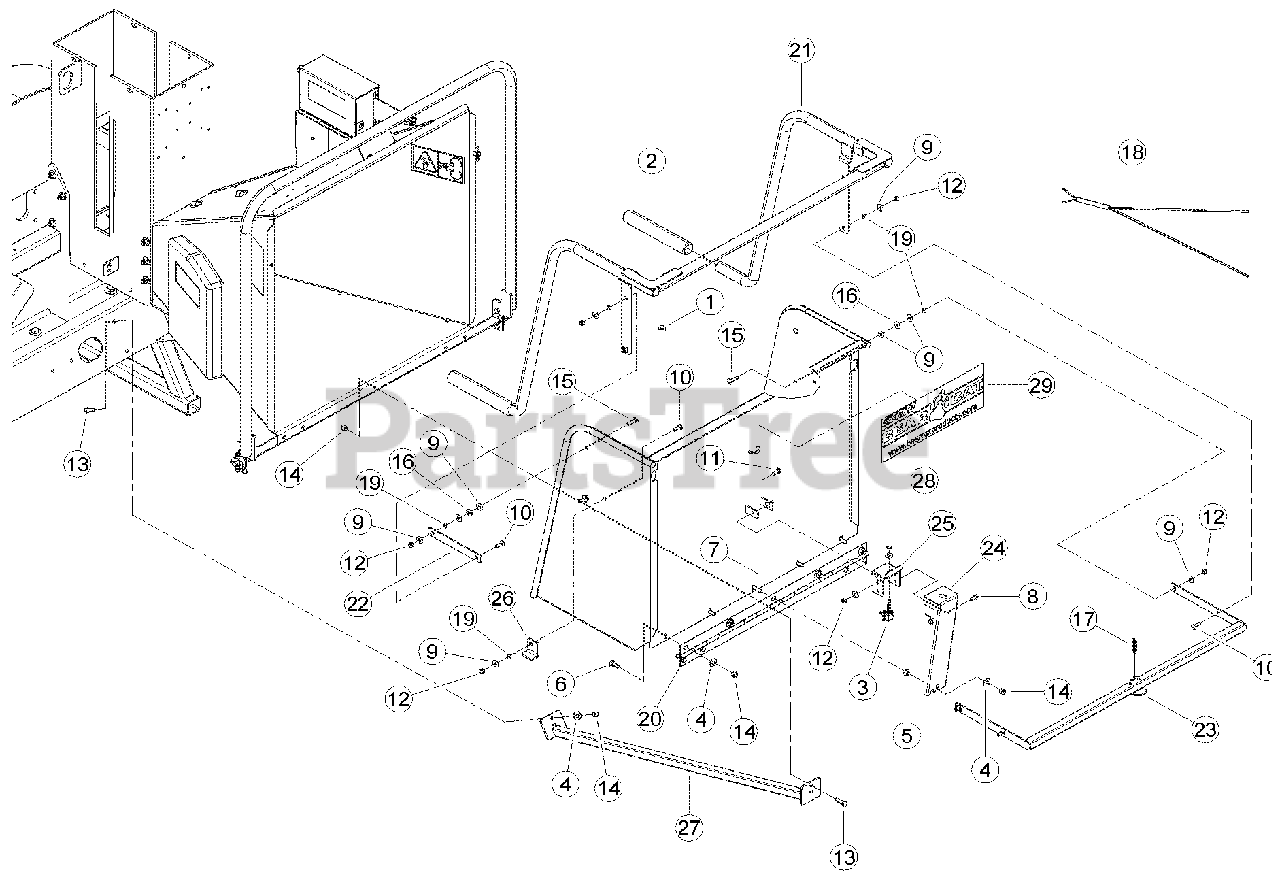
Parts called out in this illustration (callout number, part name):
1	BUMPER, RUBBER
2	GRIP, 1.219 X 10.00
3	SWITCH, MOMENTARY IP67. (FOR SERVICE ORDER KIT #77536-00)
4	WASHER, 3/8 FLAT ZP
5	NUT, 3/8 SERR FLANGE NC ZP
6	BOLT, 3/8 X 1 CRG GR5 NC ZP
7	BOLT, 3/8 X 1-1/2 CRG GR5 NC ZP
8	SCREW, 11/32 X 7/8 HWH AB THREAD ZP
9	WASHER, 5/16 FLAT ZP
10	BOLT, 5/16 X 1 CRG GR5 ZP
11	BOLT,5/16 X 7/8 CRG GR5 NC ZP
12	NUT, 5/16 NE NYLOCK ZP
13	BOLT, 3/8 X 1-1/4 HEX HD GR5 ZP
14	NUT, 3/8 NE NYLOCK ZP
15	BOLT, 5/16 X 1-1/4 CRG GR5 ZP
16	WASHER, 5/16 ID 7/8 OD NYLON FLAT
17	SPRING, 1/2 X 2.00 LONG ZP
18	HARNESS, SAFETY BAR
19	SPACER, IDLER PIVOT
20	HINGE, EXTENSION TRAY
21	WELDMENT, KNEEBAR
22	LINK, PARALLEL
23	WELDMENT, KNEEBAR PIVOT
24	SHIELD, KNEEBAR SWITCH
25	BRACKET, SWITCH. (WAS 77532-12. REPLACED AND SUPERSEDED. FOR SERVICE, ORDER KIT #77536- 0, CONTROL SWITCHES)
26	LOCK, SAFETY BAR
27	WELDMENT, CHUTE SUPPORT
28	ASSEMBLY, EXTENSION TRAY, SERVICE PART
29	DECAL, BEARCAT WEB
